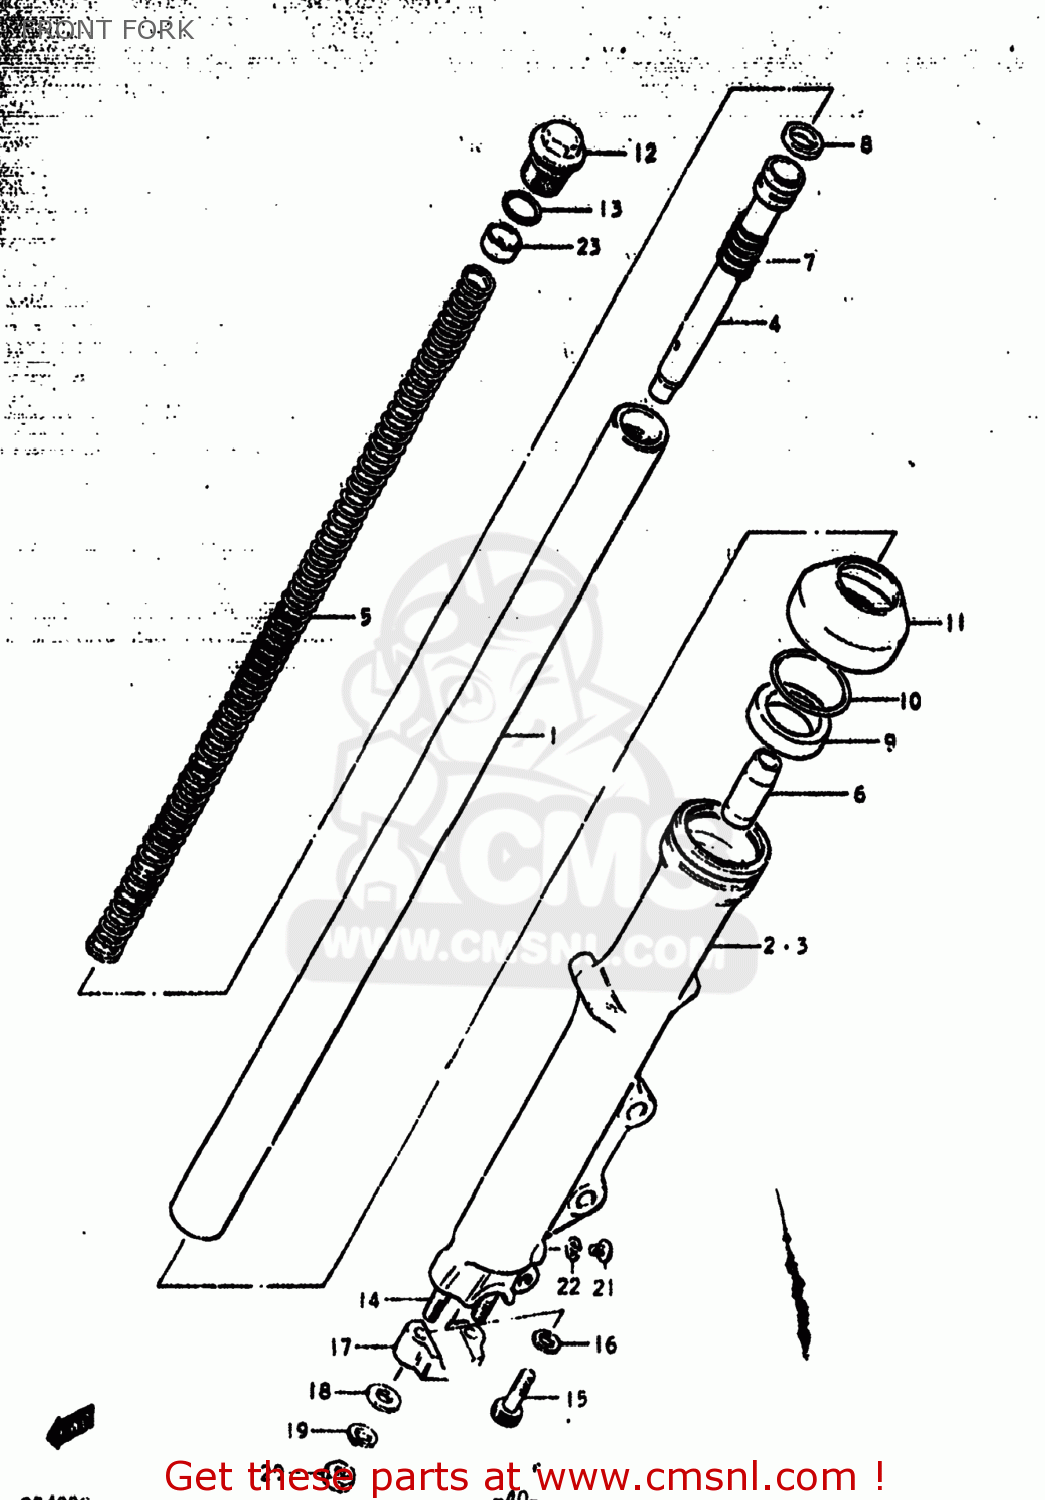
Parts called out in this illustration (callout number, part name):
0	DAMPER ASSEMBLY,LEFT
1	TUBE,INNER
2	TUBE,OUTER,LEFT
3	TUBE,OUTER,RIGHT
4	CYLINDER,FRONT FORK
5	SPRING
6	PIECE,OIL LOCK
7	SPRING,REBOUND
8	RING,PISTON
9	OIL SEAL,FRONT FORK
10	CIRCLIP,FORK OIL SEAL
11	BOOT
12	BOLT,STEERING STEM HEAD
13	O RING
14	STUD 8X25
15	BOLT
16	GASKET (NAS)
17	HOLDER,AXLE
18	WASHER
19	LOCK WASHER
20	NUT
21	SCREW
22	GASKET (NAS)
23	SPACER,FRONT FORK SPRING
